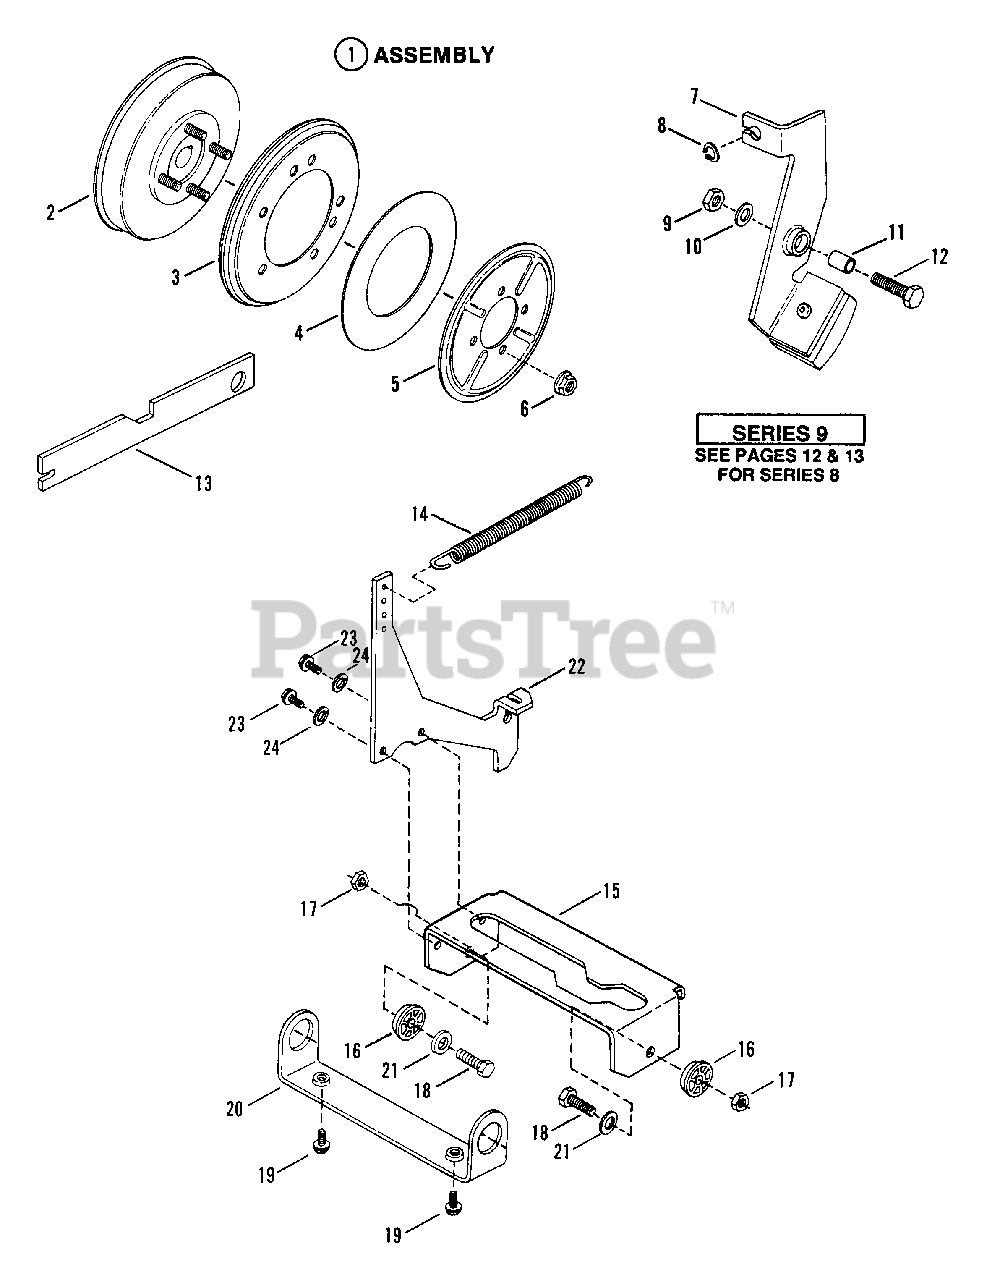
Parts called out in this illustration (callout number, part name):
1	ASSEMBLY, Smooth Clutch
2	HUB, Driven Disc
3	DISC, Driven
4	WASHER, Thrust
5	PLATE
6	NUT, 5/16 - 18 Hex Flange Lock
7	ASSEMBLY, Brake Lever
8	RING, Retaining
9	NUT, 1/4 - 28 Hex Lock
10	WASHER, 1/4 Flat
11	SPACER
12	SCREW, 1/4 - 28 x 1" Hex Head Cap
13	* TOOL, Smooth Clutch
14	SPRING, Clutch Brake
15	LIFT, Yoke
16	BEARING, Yoke
17	NUT, 5/16 - 24 Hex Lock
18	SCREW, 5/16-24 x 3/4" Hex Head Cap
19	SCREW, 3/8 - 16 x 1/2" Self-Tapping
20	COLLAR, Yoke
21	WASHER, 5/16 Flat
22	ARM, Yoke
23	SCREW, 5/16 - 18 x 1/2" Hex Head Self-Tapping
24	WASHER, 5/16 Split Lock
